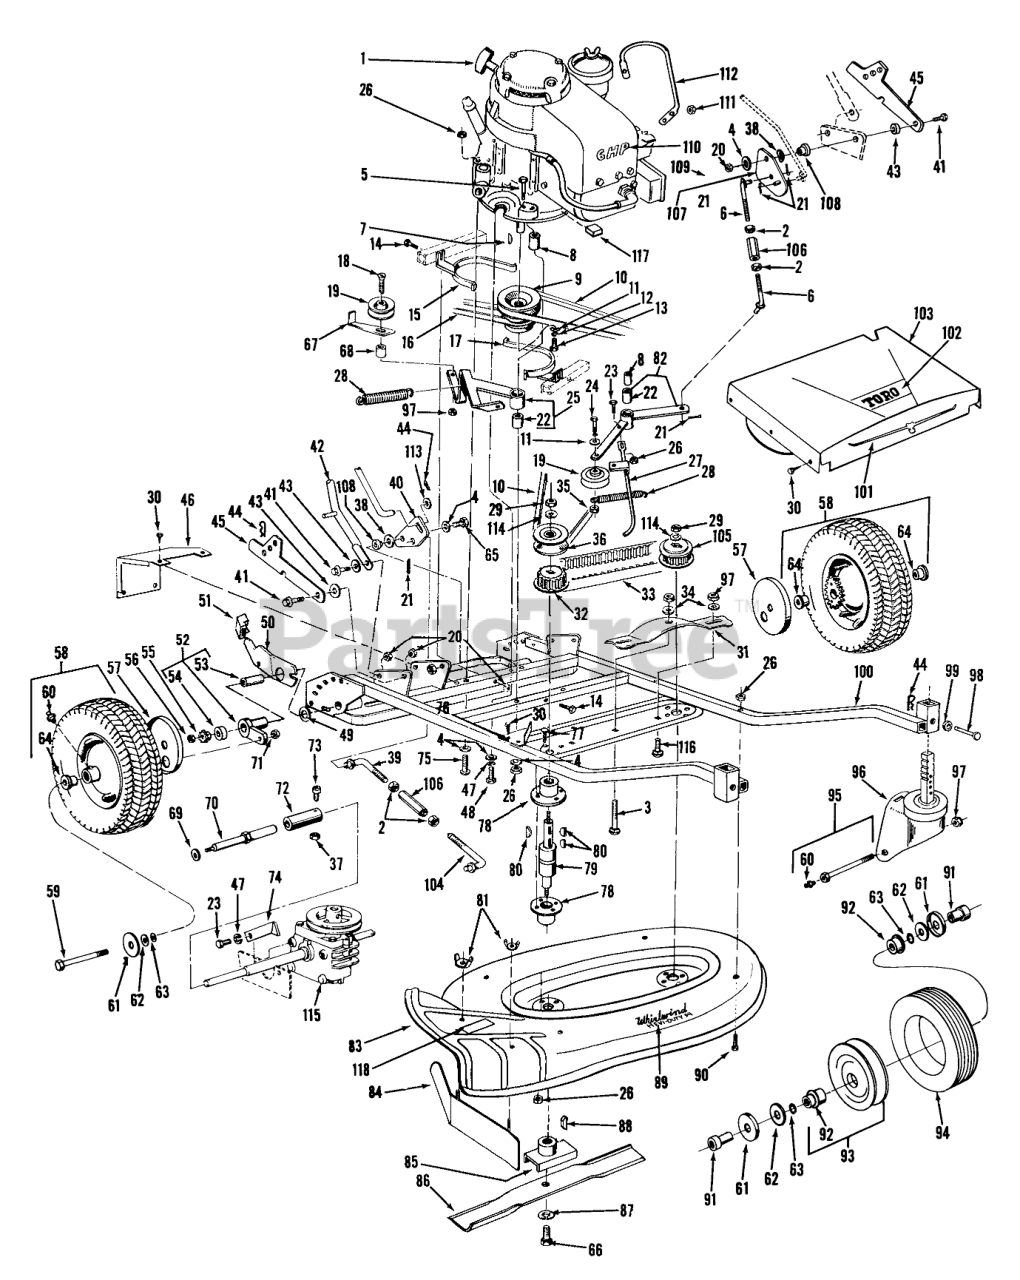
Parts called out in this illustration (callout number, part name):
1	Engine
2	NUT-HEX
3	SCREW-CARR
4	WASHER-PLAIN
5	SCREW-HH
6	TRACTION LINK
7	KEY-WOODRUFF
8	ENGINE PIVOT SPACER
9	Pulley
10	CUTTER BELT
11	WASHER-FLAT
12	WASHER-LOCK
13	SCREW-HH
14	SCREW-HH
15	Retainer, Belt
16	TRACTION BELT
17	Retainer, Belt
18	SCREW-HH
19	IDLER PULLEY R
20	NUT-LOCK, NI
21	PIN-COTTER
22	BUSHING
23	SCREW-HH
24	Screw
25	Arm & Bushing Assy.
26	NUT-LOCK, NI
27	Brake Arm
28	EXTENSION SPRING
29	NUT-LOCK, NI
30	10-16 X 3/8 THDG SCREW
31	Plate, Spreader
32	Pulley
34	WASHER-FLAT
35	NUT-HEX
36	Pulley
37	NUT-LOCK, NI
38	WASHER
39	TRACTION LINK
40	Bell Crank
41	SCREW-SHOULDER
42	Lower Handle Assy.
43	SPACER
44	PIN-COTTER
45	Latch
46	Rear Shroud
47	WASHER-LOCK
48	SCREW-HH
49	WASHER
50	RH SPRING ARM ASM
50	LH SPRING ARM ASM
51	ARM KNOB
52	Pivot Arm
53	BUSHING
54	.375 RPP BALL BEARING
55	Pinion Kit
56	NUT-HJ
57	Wheel Cover
58	REAR WHEEL & TIRE ASM
59	Axle Bolt Use on Serial No. 1 thru 250
59	SCREW-HH
60	FITTING-GREASE
61	SLINGER
62	Washer
63	O-RING
64	BEARING-BALL
64	BEARING
65	Screw-HH
66	SPECIAL SCREW
68	Spacer
69	Washer
70	DRIVE SPINDLE
71	NUT-LOCK, NI
72	Clutch Assy.
73	DRIVE SCREW
74	Retainer
75	SCREW-HH
76	Belt Retainer
77	Bolt
78	Bearing Housing
79	Bearing, Spindle-Right
80	KEY-WOODRUFF
81	NUT-WING SPECL
82	Arm & Bushing Assy.
83	Housing
84	Leaf Mulcher
85	BLADE RETAINER WA
86	18 BLADE
87	Lockwasher
89	Decal
91	Spacer
92	BEARING-BALL
93	Wheel Disc (Incl. Ref. No. 92)
94	1.75-8 SEMIPNEU TIRE
95	Axle Bolt w/Zerk
96	Caster
97	NUT-LOCK, NI
99	Grommet
100	Frame
101	Decal
102	Decal
103	Shroud
105	Pulley
106	CONTROL ROD SLEEVE
107	Bellcrank
108	PIVOT
109	SCREW-HWH, THREAD CUT
110	Decal
111	NUT-LOCK
113	Spacer
114	WASHER-TOOTH, INTERNAL
115	Transmission Assembly
116	BOLT-CARR
117	Spacer
118	Decal
